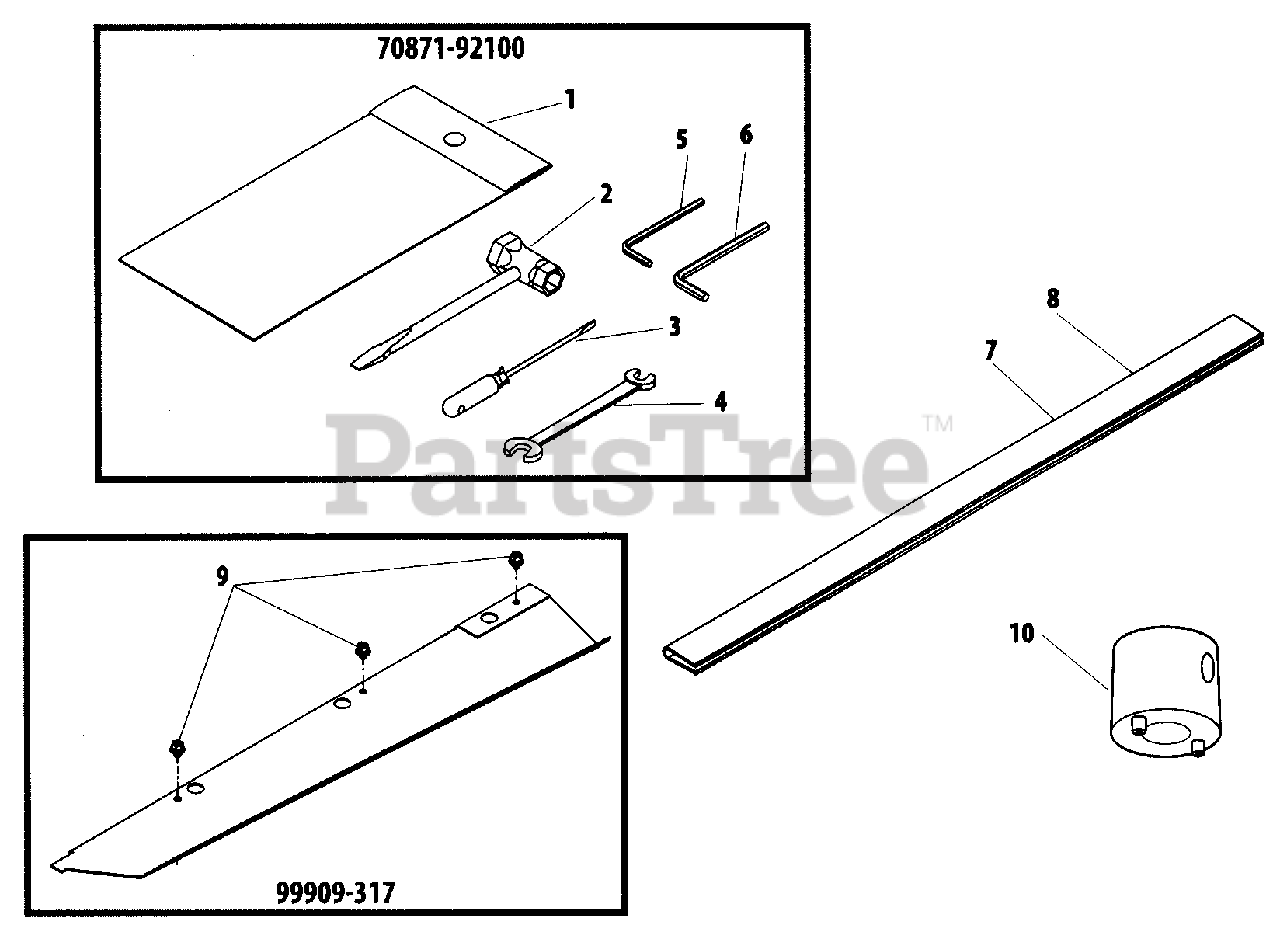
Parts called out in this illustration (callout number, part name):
1	BAG, TOOL
2	T-WRENCH
3	SCREWDRIVER
4	SPANNER - 8X10mm
5	HEX KEY - 4mm
6	HEX KEY - 6mm
7	COVER, BLADE - 30" (76cm)
8	COVER, BLADE - 40" (102cm)
9	BOLT - 5X8
10	CLUTCH DRUM WRENCH
70871-92100	TOOL KIT
99909-317	DEBRIS DEFLECTOR ASSY
